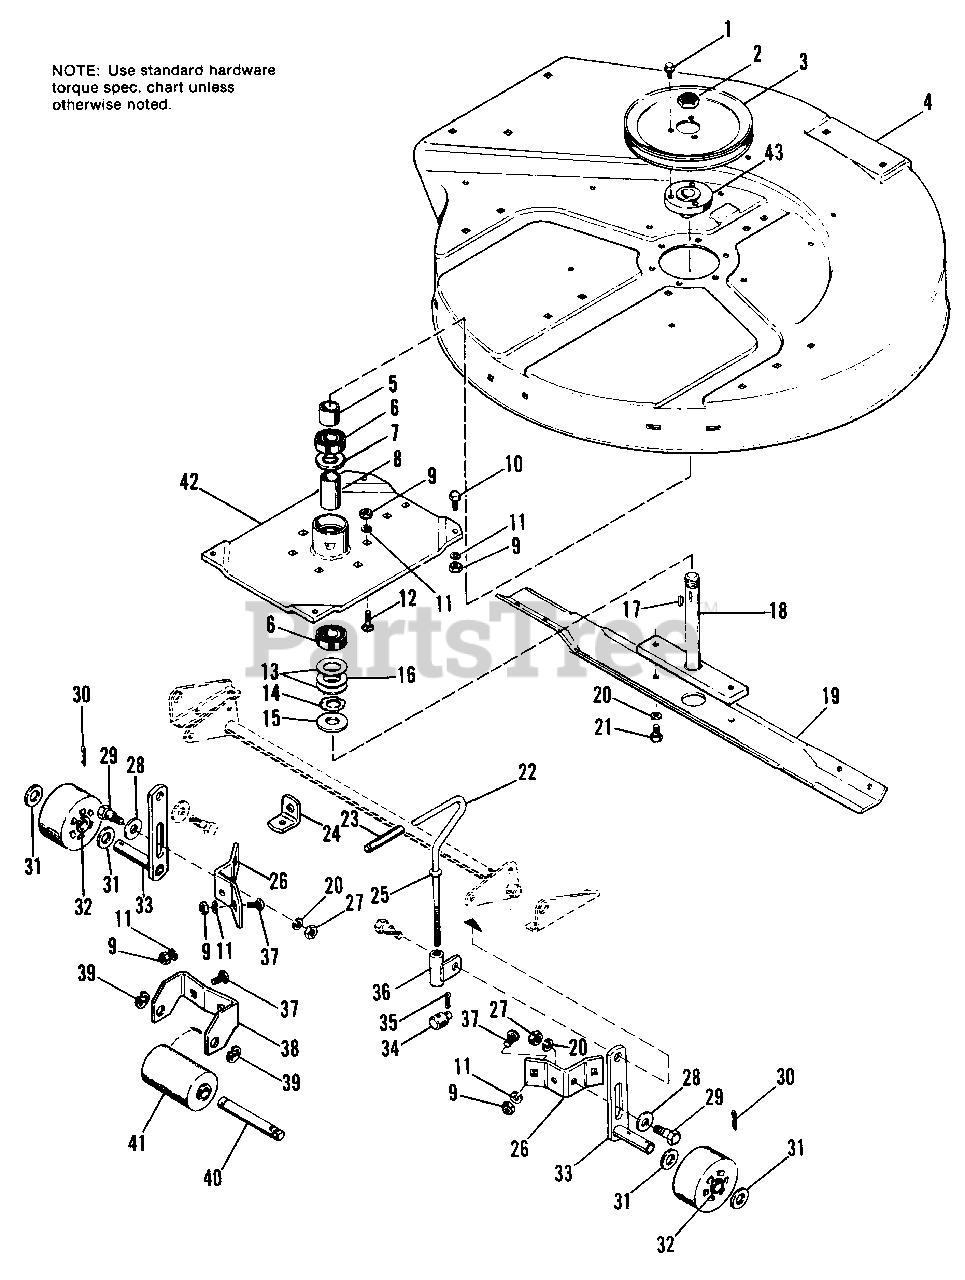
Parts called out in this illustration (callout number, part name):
1	SCREW, Thd. Forming
2	LOCKNUT, Hex, 3/4-16
3	PULLEY, Mower
4	HOUSING, 30" Mower
6	BEARING, Ball
7	RING, Backing
9	NUT, Hex, Full, 5/16-18
10	CAPSCREW, Hex Hd., 5/16-18 x 1
11	LOCKWASHER, 5/16
12	BOLT, Carriage, 5/16-18 x 1
17	KEY, Woodruff, #61
18	ARBOR ASSY.
19	BLADE, 30"
20	LOCKWASHER, 3/8
21	CAPSCREW, Hex Hd., 3/8-16 x 1
22	HANDLE, Adjusting
23	GRIP, Handle
25	WASHER, Plain, 3/8
26	BRACKET, Roller Support
27	NUT, Hex, Full, 3/8-16
28	WASHER, Plain, 7/16
29	BOLT, Shoulder, 3/8-16 X 1.34
30	PIN, Cotter, 3/16 x 1
31	WASHER, Plain, 5/8
32	ROLLER ASSY.
33	SHAFT ASSY., Roller
35	PIN, Cotter, 3/32 x 1
36	GUIDE ASSY., Rod
37	BOLT, Carriage, 5/16-18 x 5/8
38	BRACKET, Center Roller
39	RING, Retaining
40	SHAFT, Center Roller
41	ROLLER ASSY.
42	TUBE ASSY., Arbor
43	HUB, Pulley
